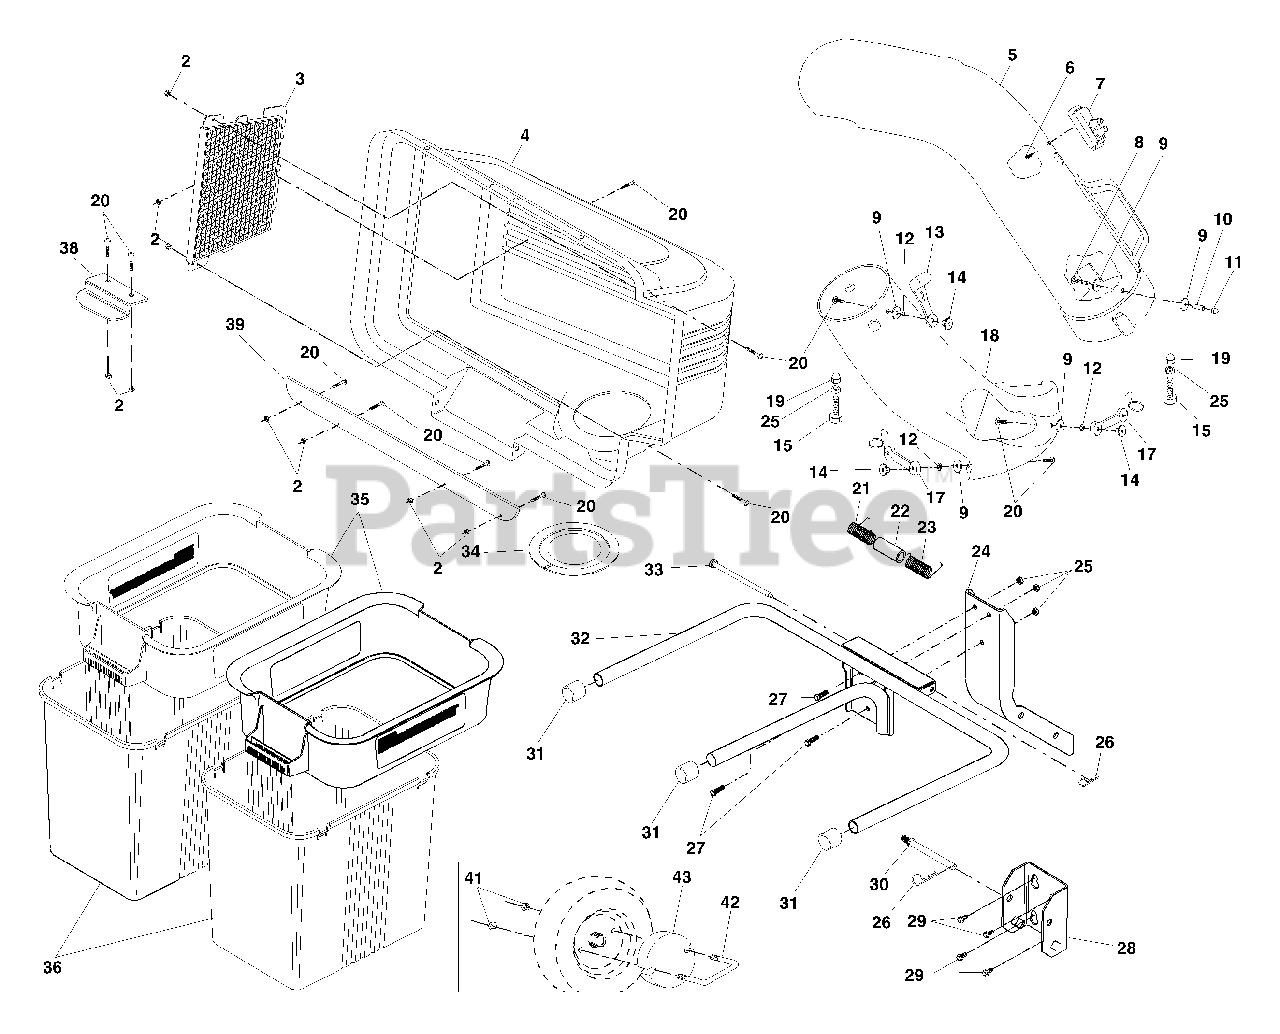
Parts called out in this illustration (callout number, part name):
2	Locknut #10-24
3	Screen, Cover
4	Cover Asm.
5	Chute, Upper
6	Screw, Special
7	Indicator, Dump Bag
8	Screw, #10-24 x 1-1/8
9	Washer 3/16 x 3/4 x 16 Ga.
10	Spacer, Split
11	Nut, Acorn #10-24
12	Washer, lock
13	Latch, Chute
14	Nut, Weld
15	Bolt, Hex 5/16-18 x 1
17	Latch Assy., Bagger
18	Chute, Lower
19	Nut, Acorn 5/16-18
20	Screw #10-24 x 5/8
21	Spring, Cover L.H. (black)
22	Spacer, Cover
23	Spring, Cover R.H. (gray)
24	Post, Support
25	Locknut 5/16 x 18
26	Spring, Retainer
27	Bolt, Carriage 5/16-18 x 3/4
28	Bracket, Mounting
29	Shoulder Bolt, Self-Tapping
30	Pin, Support Post
31	Cap, Tubing End
32	Bagger, Frame
33	Pin, Hinge
34	Gasket, Cover
35	Container, Top
36	Container, Bottom
38	Latch Handle, Cover
39	Strip, Reinforcement
41	Locknut 3/8-16
43	Weight, Wheel
